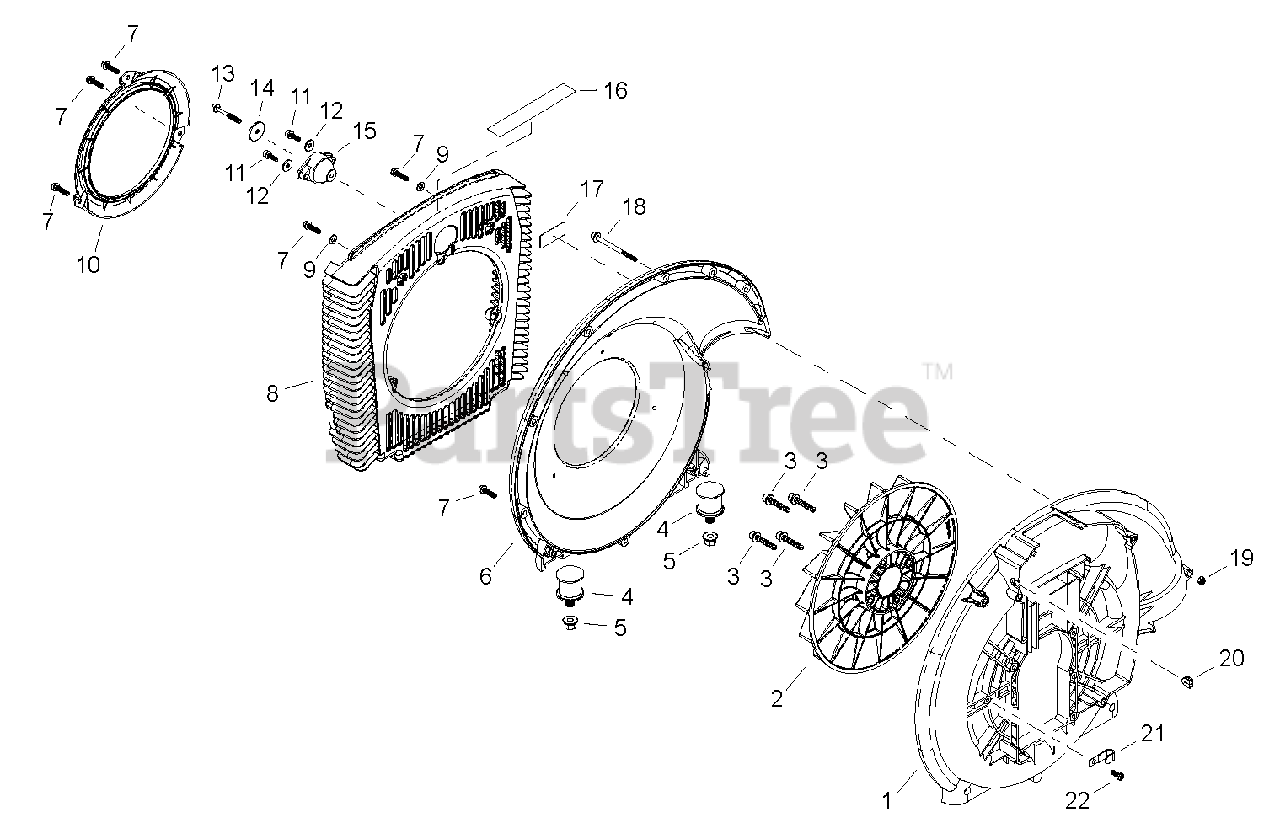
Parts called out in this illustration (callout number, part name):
1	CASE, FAN
2	FAN
3	BOLT M6×35
4	CUSHION, AV 6
5	NUT, FLANGE M6
6	COVER, FAN
7	BOLT M5×20
8	GUARD, DEBRIS
9	WASHER 5 MM
10	COVER, DEBRIS GUARD
11	BOLT M5×16
12	WASHER Ø15ר5.2×1.6
13	BOLT TAPPING M5
14	WASHER Ø25ר5.5×2
15	CUSHION, AV 5
16	LABEL, CAUTION
17	LABEL, CAUTION - AIR INTAKE
18	BOLT M5×70
19	NUT M5
20	GROMMET
21	CLIP
22	SCREW, TAPPING 5×14
